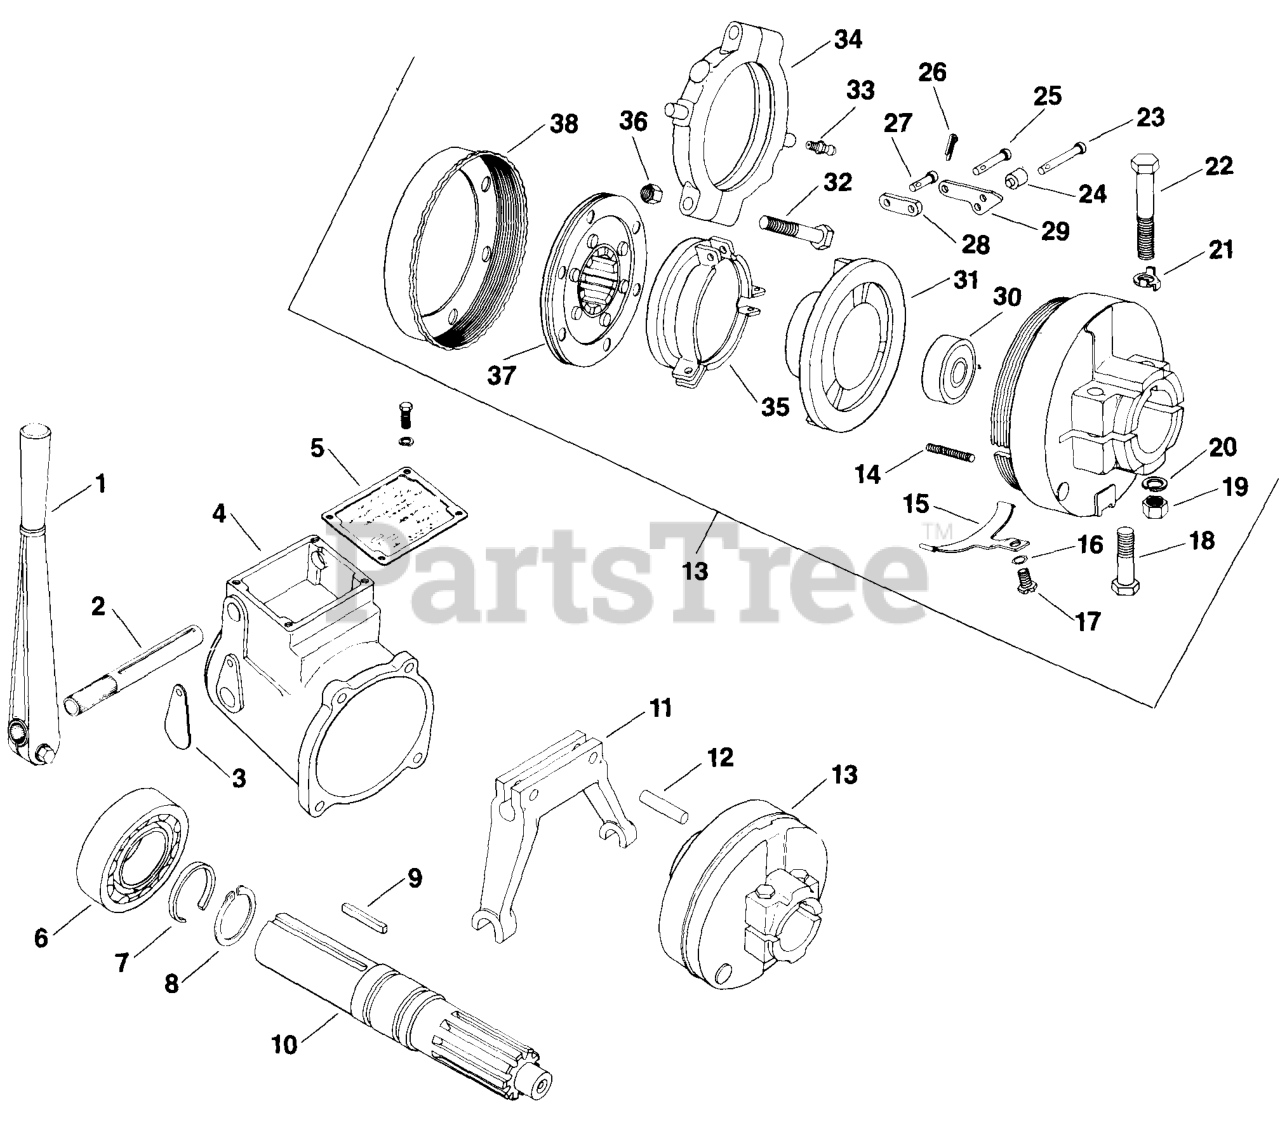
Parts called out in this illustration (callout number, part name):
1	LEVER - DISCONTINUED
2	SHAFT - DISCONTINUED
5	Nameplate, housing
6	BEARING - DISCONTINUED
7	SNAP RING - DISCONTINUED
11	YOKE - USE 24 471 01
14	SPRING - DISCONTINUED
16	WASHER, INT TOOTH LOCK 1/4"
17	SCREW - DISCONTINUED
19	Nut, elastic stop 3/8"
20	WASHER, SPRING LOCK 5/16"
21	LOCK - DISCONTINUED
23	PIN - DISCONTINUED
24	ROLLER - DISCONTINUED
25	PIN - DISCONTINUED
28	LINK - DISCONTINUED
30	Searing, pilot
32	Screw, hex. hd. 5/16-24 x 1-3/4"
34	BEARING - DISCONTINUED
